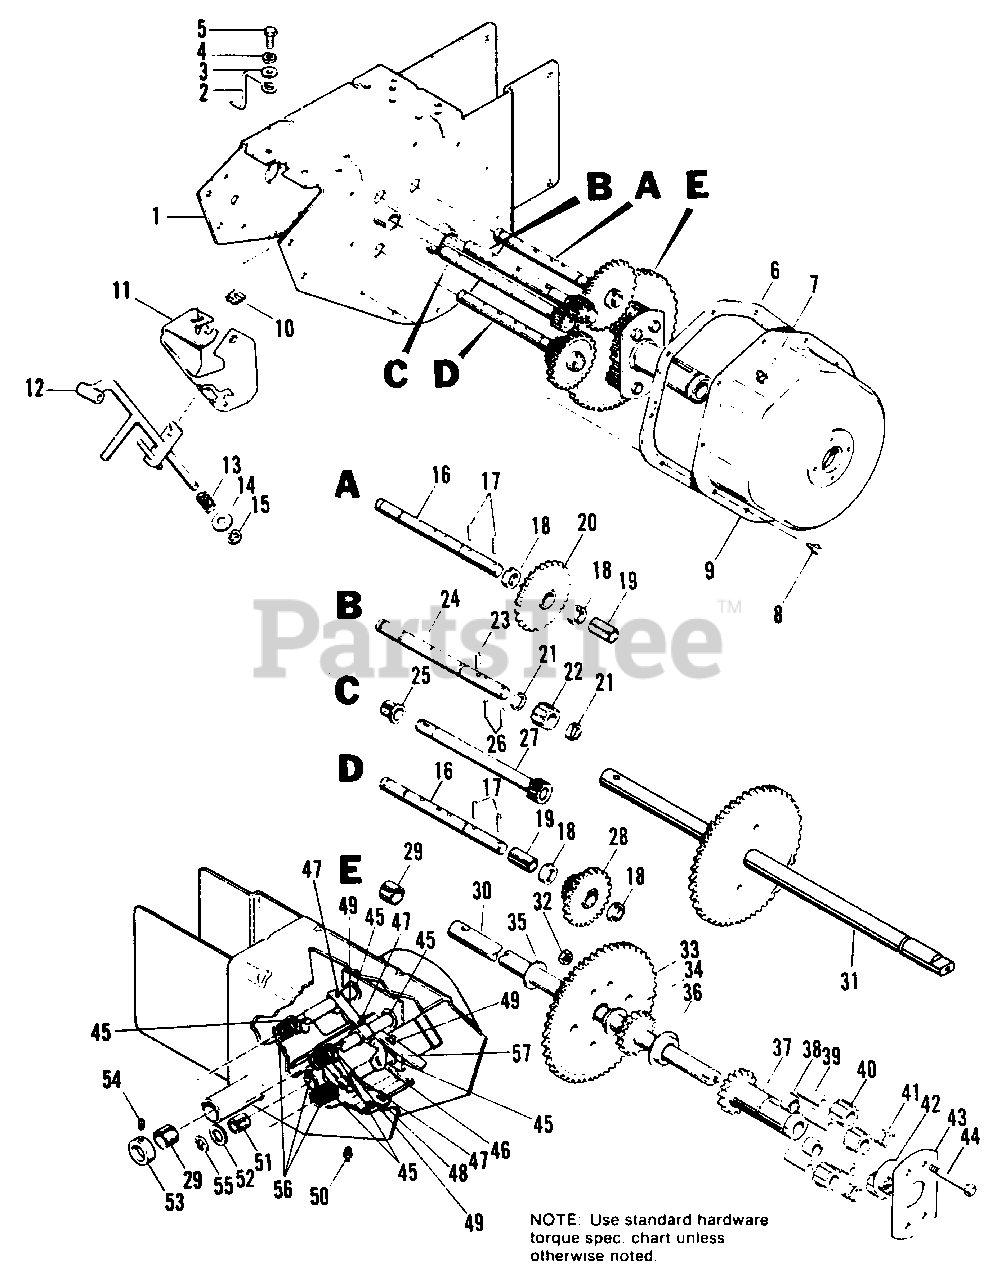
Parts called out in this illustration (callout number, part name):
1	ENGINE BASE & FRAME ASSY.
2	STOP, Belt
3	WASHER, Plain, 1/4
4	LOCKWASHER, 5/16
5	CAPSCREW, Hex Hd., 5/16-18
7	FITTING, Grease
8	SCREW, Taptite 1/4-20 x 3/8
9	CASE ASSY., Gear (990643 & 990796 Only)
9	CASE ASSY., Gear
10	NUT, Retainer, 5/16-18
11	GUIDE, Pattern
12	SHIFT ROD ASSY., Lower
14	WASHER, Plain, 7/16
15	RING, Retaining
16	SHAFT, Intermediate
17	PIN, Roll, 1/8 x 1
18	COLLAR, Thrust
20	GEAR & BEARING ASSY.
21	COLLAR, Thrust
22	PINION, Reverse
23	PIN, Roll, 5/32 x 1
24	SHAFT, Reverse
25	BEARING, Bronze
26	PIN, Roll, 1/8 x 3/4
27	SHAFT ASSY., Gear (990796 & 990869 Only)
27	SHAFT ASSY., Gear
28	GEAR & BEARING ASSY.
30	AXLE ASSY, L.H. (990643 & 990796 Only)
31	AXLE & GEAR ASSY.
32	LOCKNUT, Hex, 3/8-16 (990643 & 990796 Only)
33	GEAR, Drive (990643 & 990796 Only)
34	BUSHING (990643 & 990796 Only)
35	WASHER (990643 & 990796 Only)
36	CUP, Thrust (990643 & 990796 Only)
37	AXLE & BUSHING ASSY., R.H. (990643 & 990796 Only)
38	SPACER (990643 & 990796 Only)
39	SPINDLE (990643 & 990796 Only)
40	PINION, Diff. (990643 & 990796 Only)
41	SPRING (990643 & 990796 Only)
42	BUSHING (990643 & 990796 Only)
43	PLATE, Diff. (990643 & 990796 Only)
44	CAPSCREW, Hex Hd., 3/8-16 x 2-1/2 (990643 & 990796 Only)
45	RING, Retaining
46	LINK, Shifter Lo
47	PIN, Cotter 3/16 x 1-1/4
48	LINK, Shift, High
49	PIN, Cotter 3/32 x 3/4
50	FITTING, Grease
51	BEARING, Bronze
53	COLLAR, Set
54	SETSCREW, 5/16-18 x 3/8
55	RING, Retaining
57	LINK, Shift, Reverse
